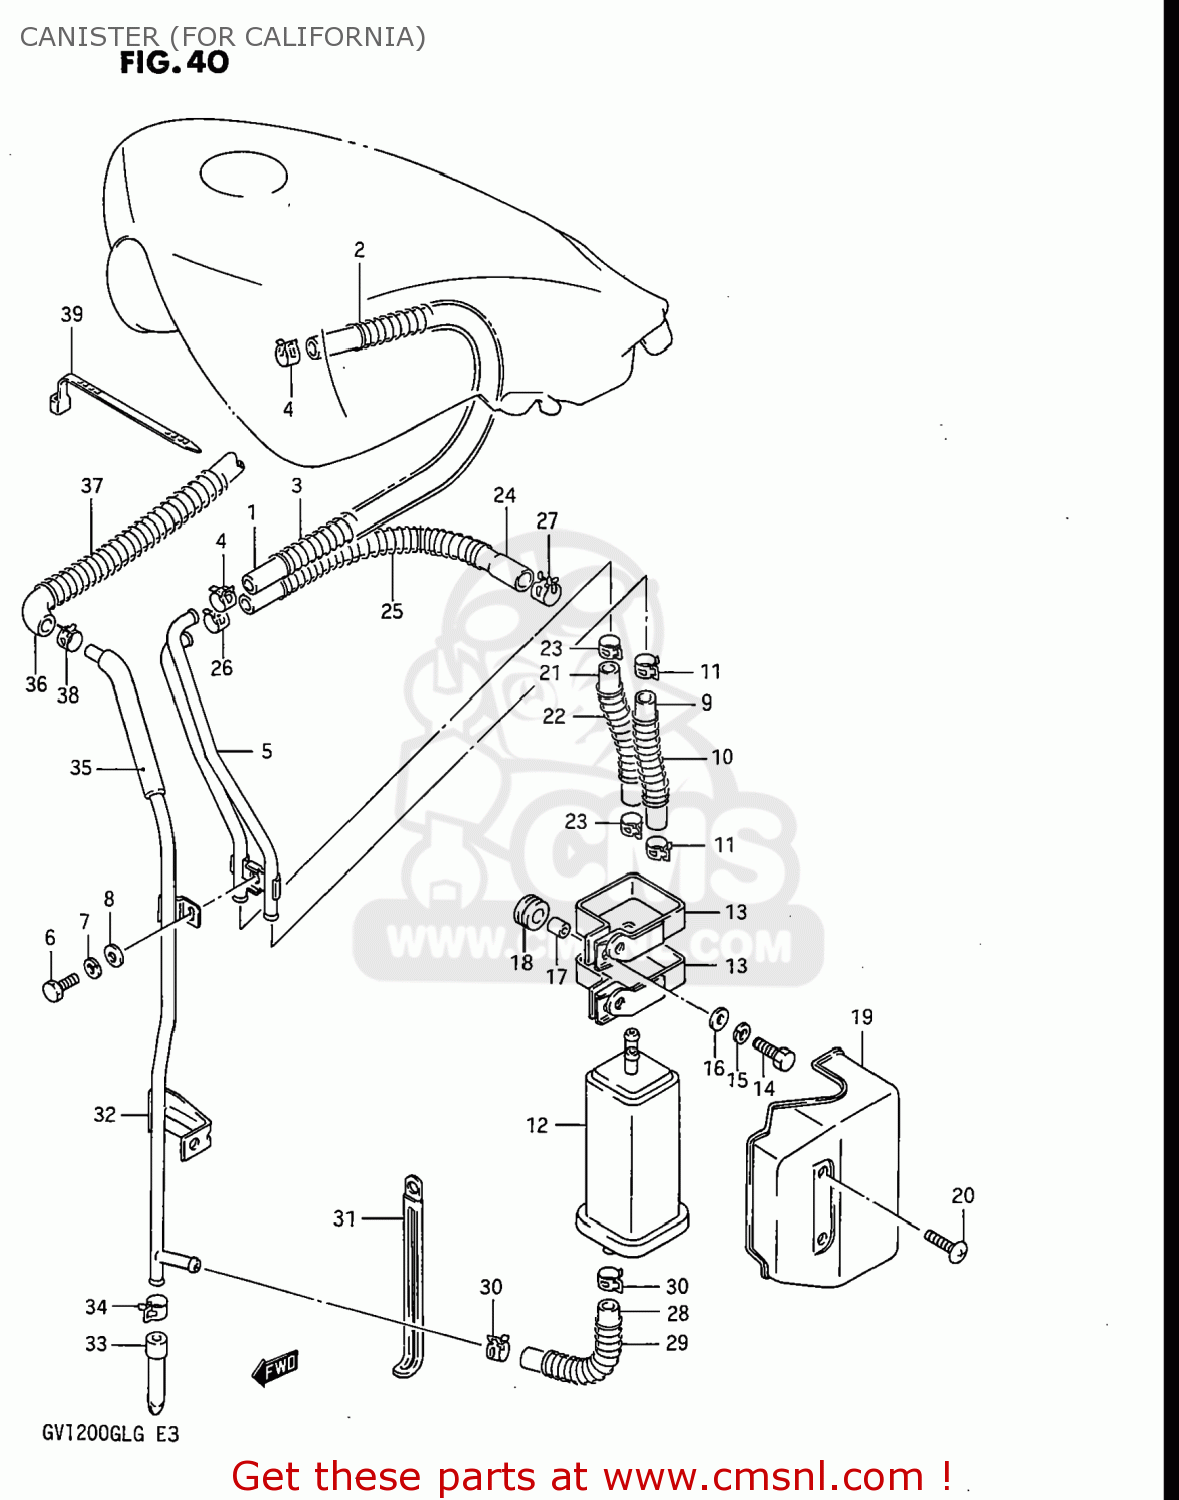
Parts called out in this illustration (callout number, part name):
1	HOSE
2	SPRING
3	(CA) SPRING
4	(CA) CLIP
5	PIPE
6	BOLT
7	WASHER,LOCK
8	WASHER
9	HOSE
10	(CA) SPRING
11	(CA) CLIP
12	(CA) CANISTER ASSEMBLY
14	BOLT
15	WASHER,LOCK
16	WASHER
17	SPACER(6.1X9X7.5)
18	CUSHION
20	SCREW
21	HOSE
22	(CA) SPRING
23	(CA) CLIP
24	HOSE
25	(CA) SPRING
26	(CA) CLIP
27	CLAMP
28	HOSE
29	(CA) SPRING
30	CLAMP
31	CLAMP
32	(CA) PIPE,CANISTER DRAIN L
33	(CA) CAP,CANISTER DRAIN
34	(CA) CLIP
35	HOSE
36	HOSE
37	(CA) SPRING
38	(CA) CLIP
39	CLAMP(L:125)
